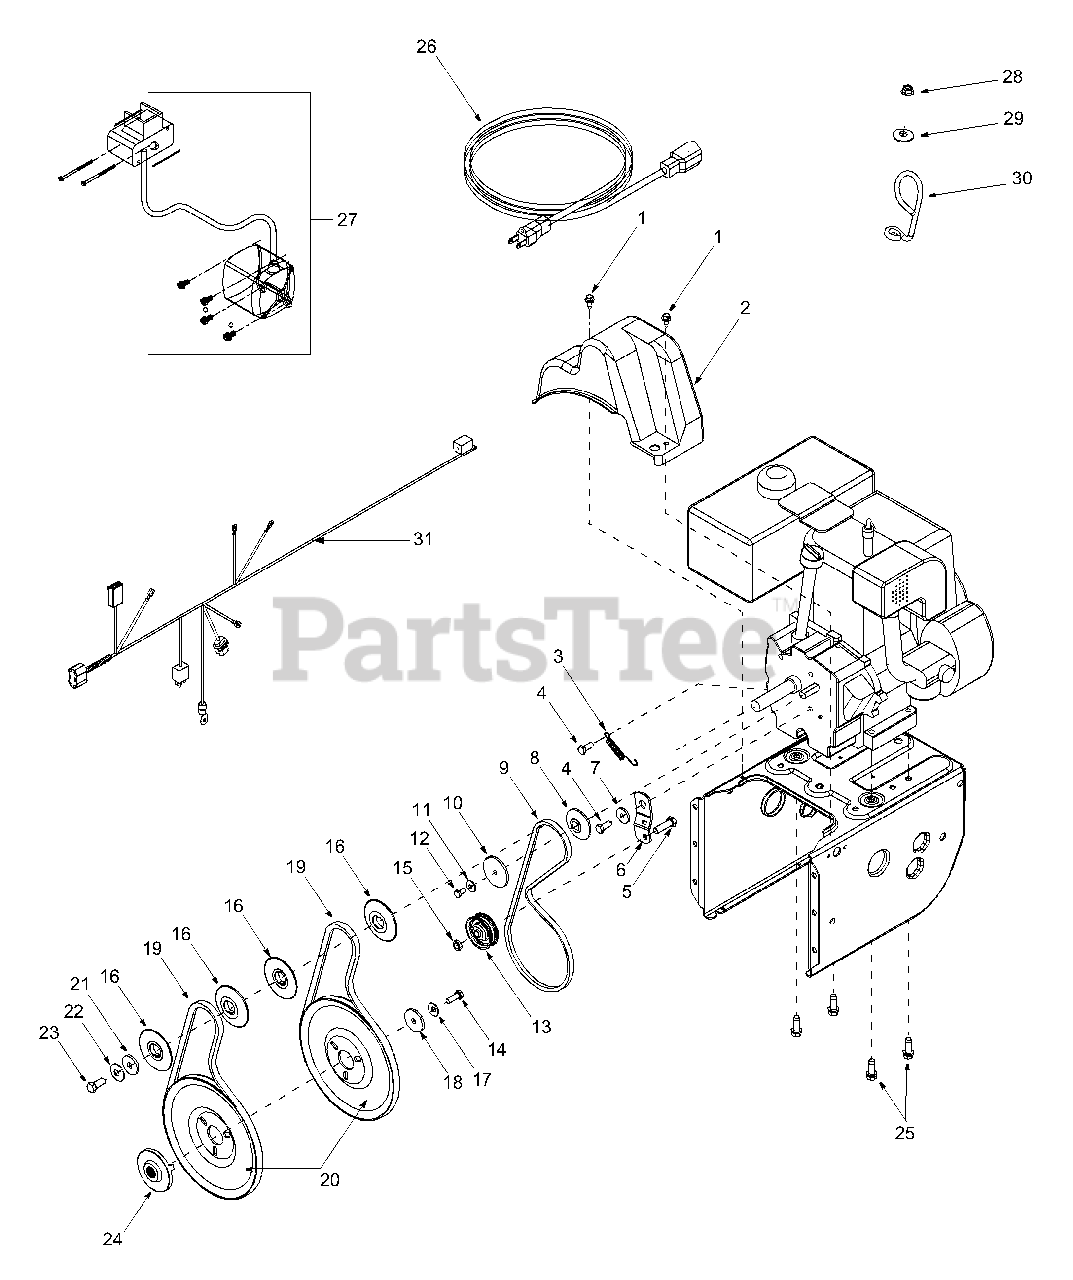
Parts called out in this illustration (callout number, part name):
1	Hex Washer Screw 1/4-20 x .625
2	Belt Cover
3	Extension Spring
4	Hex Screw 5/16-24 x .75
5	Hex Cap Screw 3/8-16 x 1.25
8	Pulley Half
9	V-Belt
10	Pulley Half
11	Bell Washer
12	Hex Cap Screw 1/4-28 x .50
13	Flat Idler
14	Lock Hex Cap Screw 5/16-24
15	Lock Jam Nut 3/8-16
16	Pulley Half
17	Bell Washer
18	Flat Washer
19	Belt
20	Auger Pulley
21	Flat Washer 3/8 x 1.25 OD
22	Bell Washer
23	Hex Cap Screw 3/8-24
24	Adapter Pulley
25	Hex Screw 3/8-16 x 1.0
26	Extension Cord
27	Electric Start Kit
28	Lock Nut, 1/4-20
29	Flat Washer, .28 x .74 x .063
30	Cable Guide
31	Upper Harness Assembly
